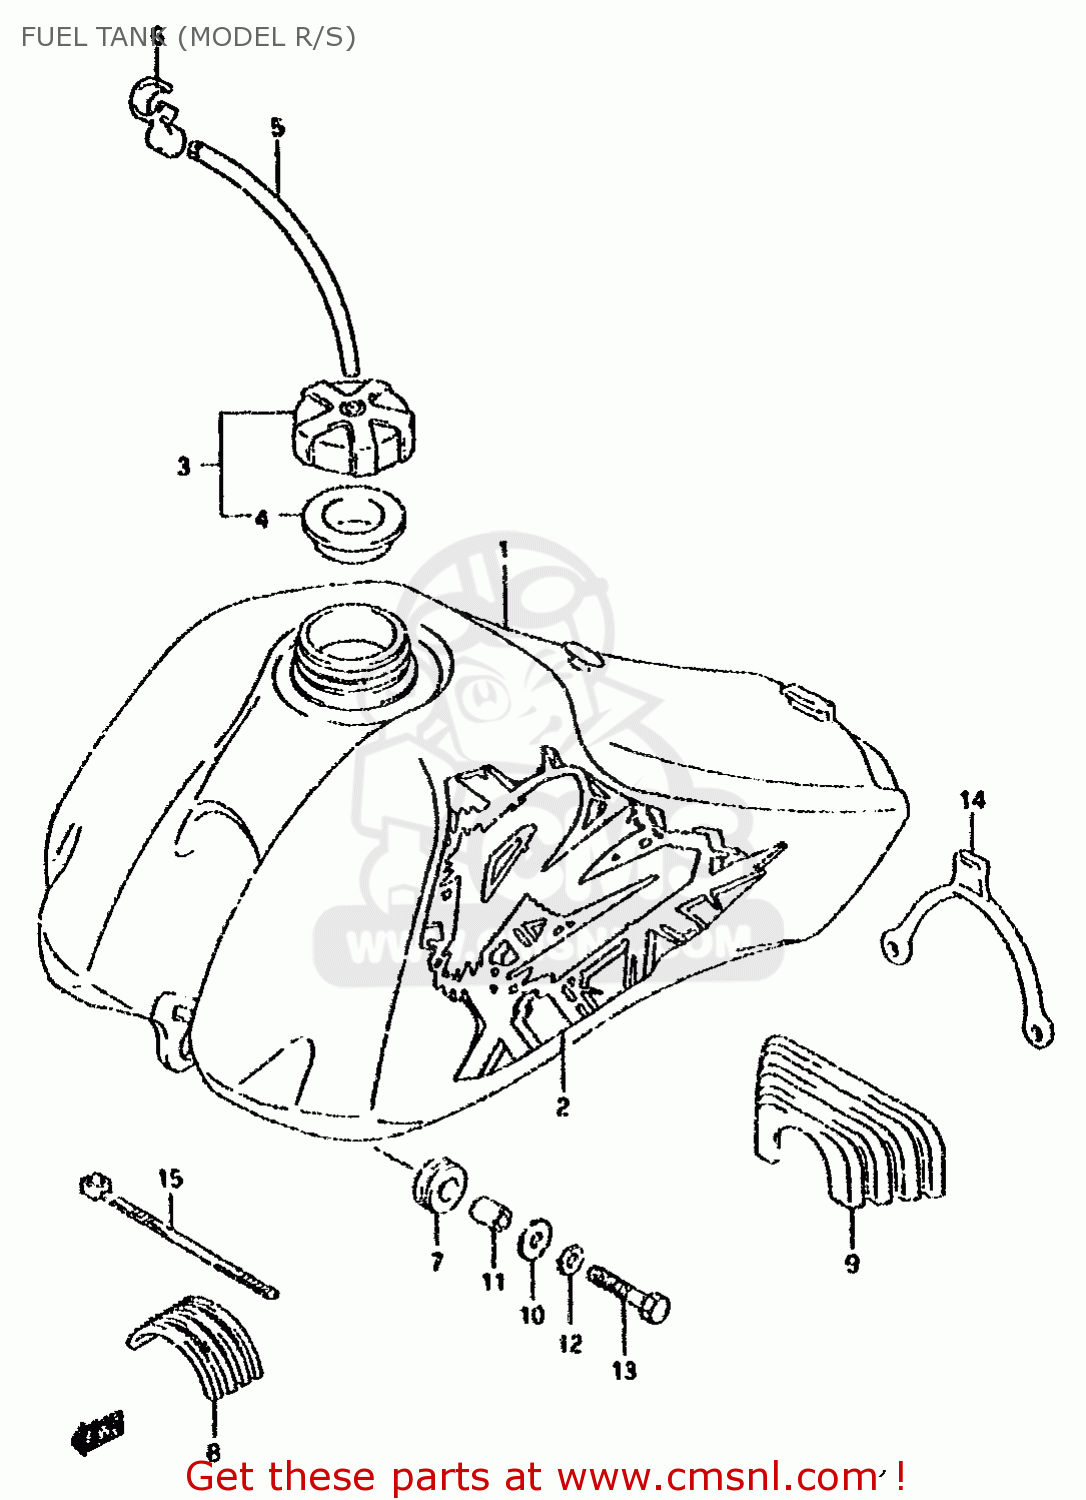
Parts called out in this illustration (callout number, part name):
1	TANK ASSY,FUEL(YELLOW)
2	EMBLEM SET,FUEL TANK
3	CAP SET,FUEL TANK
4	GASKET (NAS)
5	HOSE(5X8.2X600)
6	CLAMP
7	CUSHION
8	CUSHION,FUEL TANK UPR FR
9	CUSHION,FUEL TANK UPR RR
10	WASHER (6.5X24X1.6)
11	SPACER (6.5X10.5X13.5)
12	WASHER,LOCK
13	BOLT
14	BAND,FUEL TANK RR
15	CLAMP
19	CLAMP
